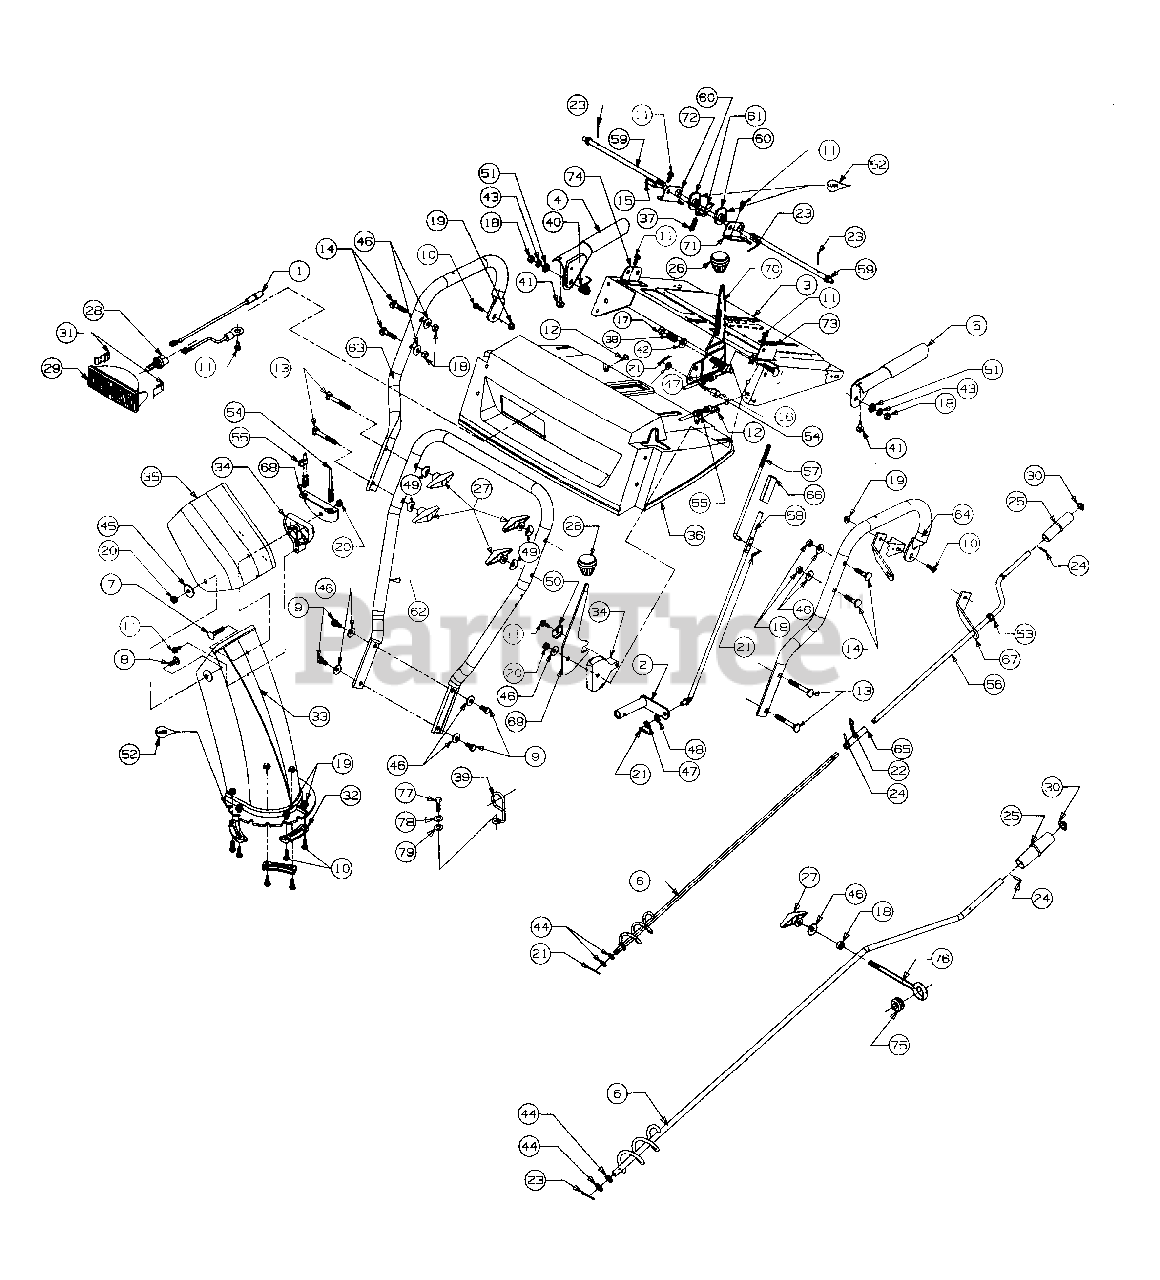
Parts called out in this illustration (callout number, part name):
1	Harness-Light
5	Handle-Engagement-L.H.
6	Crank-Chute
8	Bolt-Carriage
9	Screw-Hex
10	Screw-Hex
11	Screw-Washer Head-Hex
12	Screw-Hex
13	Bolt-Carriage
14	Bolt-Carriage
15	Pin-Clevis
16	Ferrule
17	Nut-Hex Lock
18	Nut-Hex
19	Nut-Hex Lock
20	Nut-Hex Lock
21	Pin-Cotter Internal
22	Pin-Cotter
23	Pin-Cotter
24	Pin-Roll
25	Knob-Chute Crank
26	Knob-Shift
27	Knob-Wing Nut
28	Lamp
29	Housing-Lamp
30	Cap-Push
31	Clip-Retaining
32	Keeper-Chute
33	Chute-Lower
34	Guide-Cable
35	Chute-Upper
36	Panel-Handle
37	Spring
38	Spring
39	Wire-Control
40	Spring
41	Bumper
42	Washer-Bell
43	Washer-Lock
44	Washer-Flat
45	Washer
46	Washer-Bell
47	Washer-Flat
48	Washer-Lock
49	Washer-Saddle
50	Washer
51	Washer
52	Lubricant
53	Bushing-Plastic
54	Cable-Chute Control
55	Cable-Chute Control
56	Crank-Chute
57	Rod-Shift Upper
58	Rod-Shift Lower
59	Rod-Cam
60	Cam-Handle Lock
61	Pawl-Handle Lock
66	Connector
70	Handle-Shift
75	Grommet Rubber
76	Eyebolt-Chute
77	Screw-Washer Head-Hex
78	Washer-Lock
79	Washer-Flat
